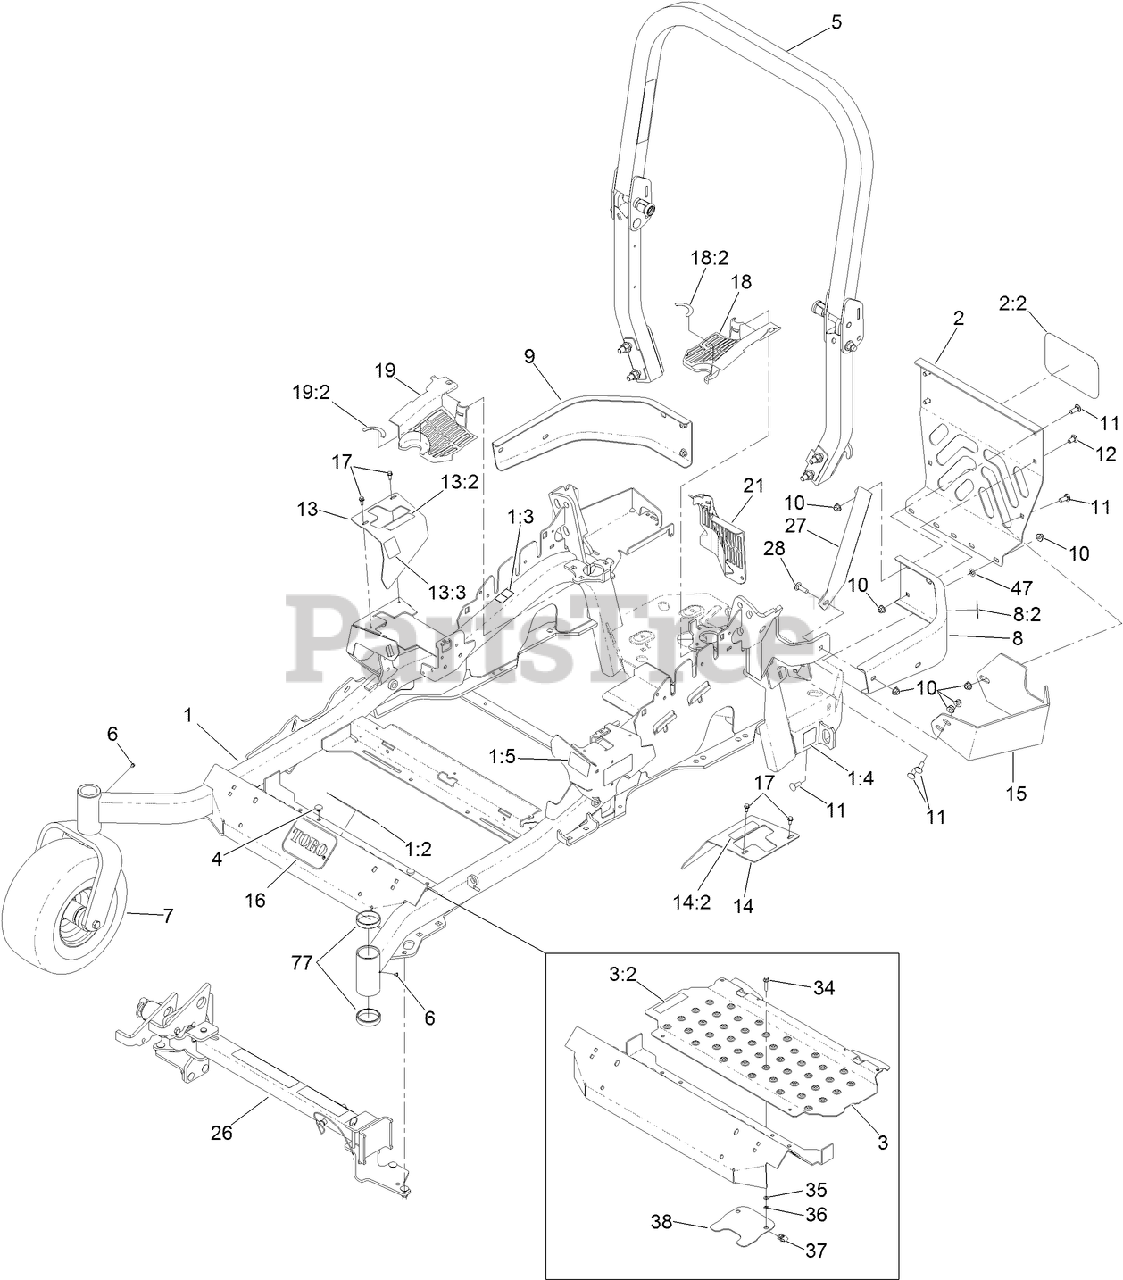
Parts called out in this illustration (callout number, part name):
1	MAIN FRAME ASM
1:2	DECAL-DANGER SLOPE W/ROPS
1:3	DECAL-WARNING
1:4	DECAL-HAZARD, PINCHED FINGER
1:5	DECAL-FUEL FILL, CE
2	REAR GUARD ASM
2:2	DECAL
3	FLOORPAN ASM
3:2	DECAL-MISSING, COVER
4	BUMPER
5	ROPS ASM
7	Caster Wheel ASM
8	LH REAR BUMPER ASM
8:2	DECAL-WARNING
9	BUMPER-RH
10	NUT-HF, NI
11	SCREW-CARR
12	SCREW-CARR
13	RH MOTION CONTROL COVER ASM
13:2	DECAL-CONTROL, MOTION
13:3	DECAL-PARK BRAKE, CE
14	LH MOTION CONTROL COVER ASM
14:2	DECAL-CONTROL, MOTION
15	GUARD-MUFFLER
16	DECAL
17	SCREW-HWH
18	LH HYDRO GUARD ASM
18:2	DECAL-HYDRO OIL
19	RH HYDRO GUARD ASM
19:2	DECAL-HYDRO OIL
21	GUARD-HYDRO, REAR (RH)
26	Z STAND ASM
28	BOLT-CARR
34	SCREW-HHF
35	WASHER-FLAT
36	NUT-RETAINER
38	ADAPTER-CAPTIVE
47	NUT-PUSH
77	CUP-BEARING
